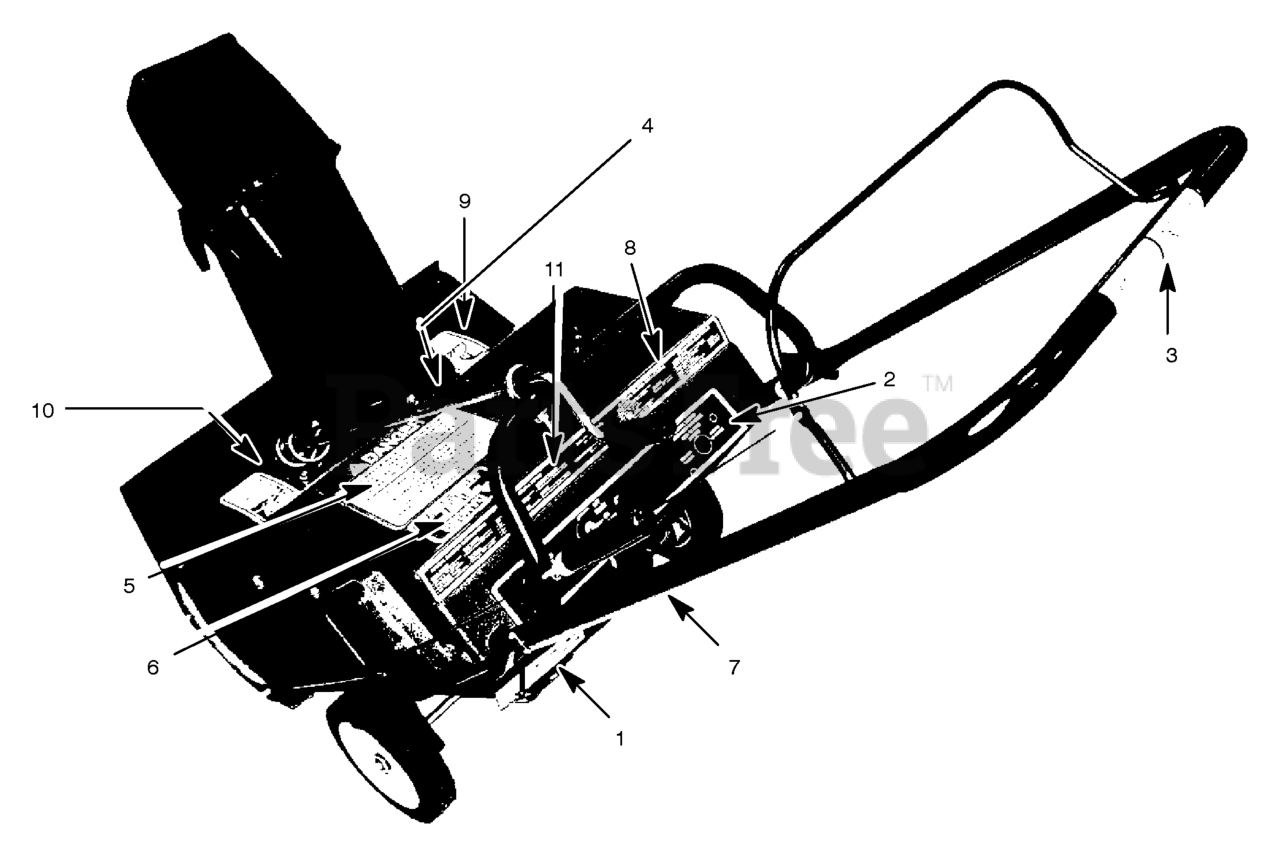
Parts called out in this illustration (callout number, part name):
1	DECAL, OFF-CHOKE-ON
2	DECAL, DANGER FOOT
3	DECAL, AUGER CONTROL
4	DECAL, CRAFTSMAN 3/20
5	DECAL, READ
6	DECAL, MUFFLER HOT
7	DECAL, EPA 3HP MASS
8	DECAL, ENGINE STARTING INSTRUCTIONS
9	DECAL, DANGER CHUTE HAND
10	DECAL, DANGER AUGER FOOT
11	DECAL, FUEL MIX SNOW
